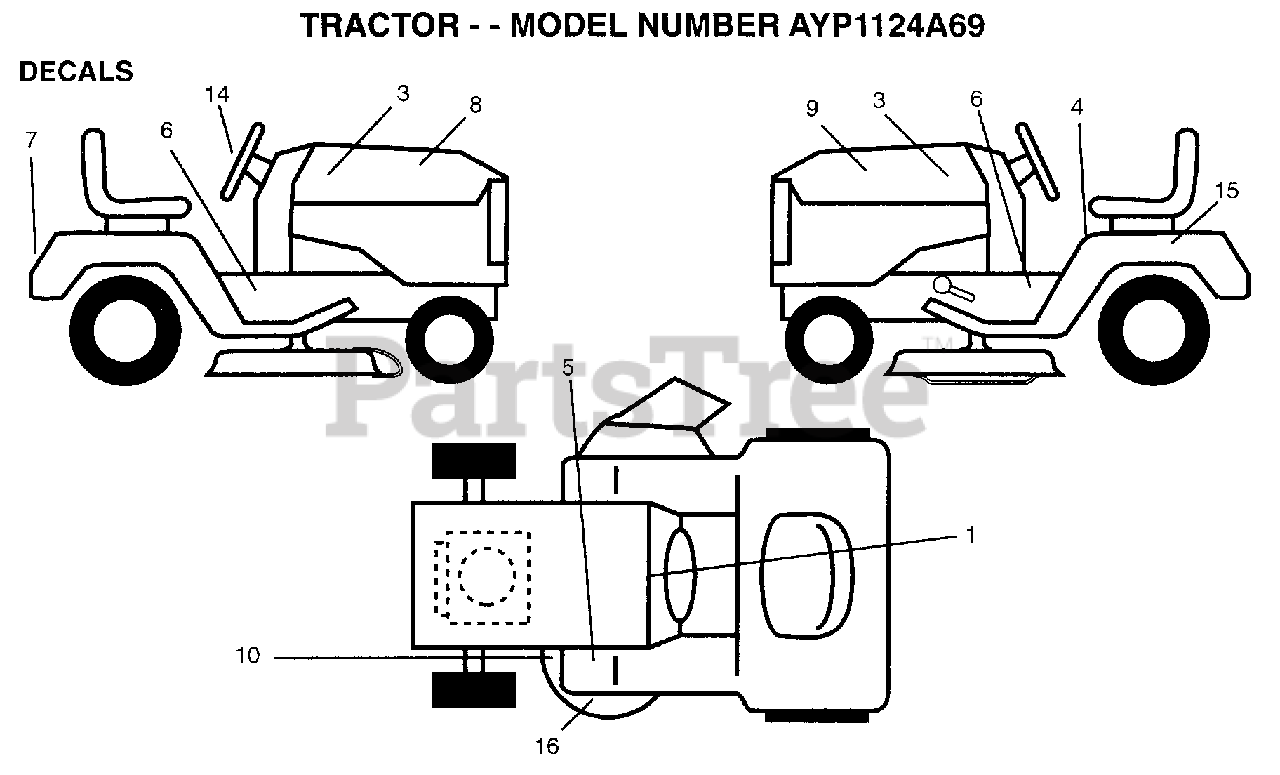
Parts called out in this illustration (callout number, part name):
3	NAMEPLATE WIZARD
4	DECAL
6	DECAL CHASSIS
8	DECAL.HD.RH.WIZAR
9	DECAL.HD.LH.WIZAR
10	DECAL
14	DECAL.INS.STRG.WL
15	DECAL.BTRY.DANGER
16	DECAL DECK WIZ +
